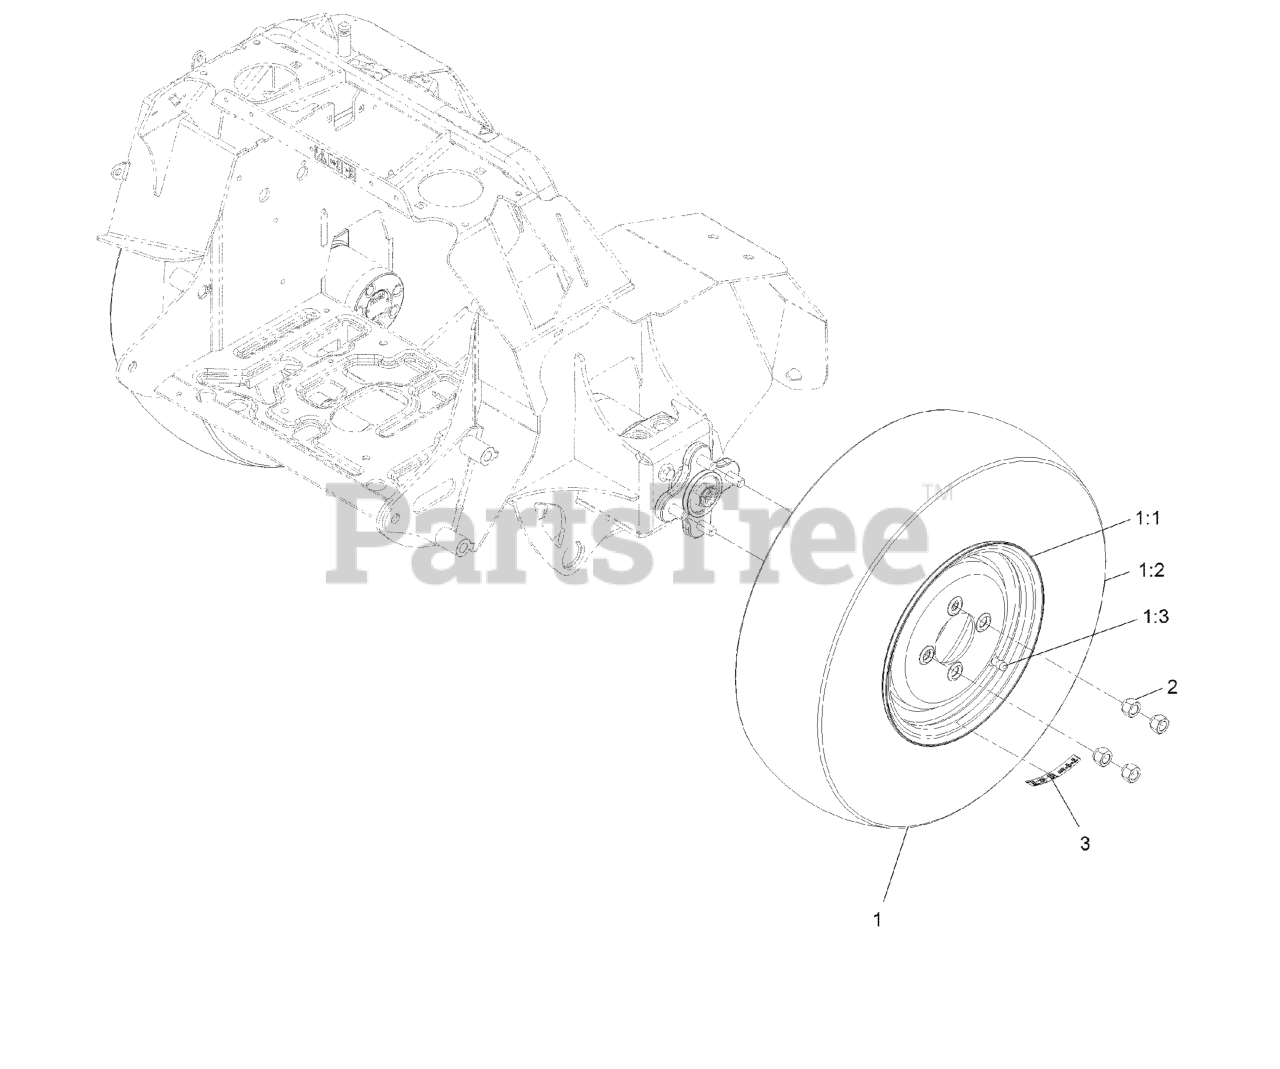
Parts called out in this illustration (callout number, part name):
1	ASM-WHL TIRE
1:1	WHEEL 10 X 5.5 WHT
1:2	TIRE 21X7.00-10
1:3	Stem-Valve
2	NUT-LUG
3	DECAL-TORQUE WHEEL LUG-HU
